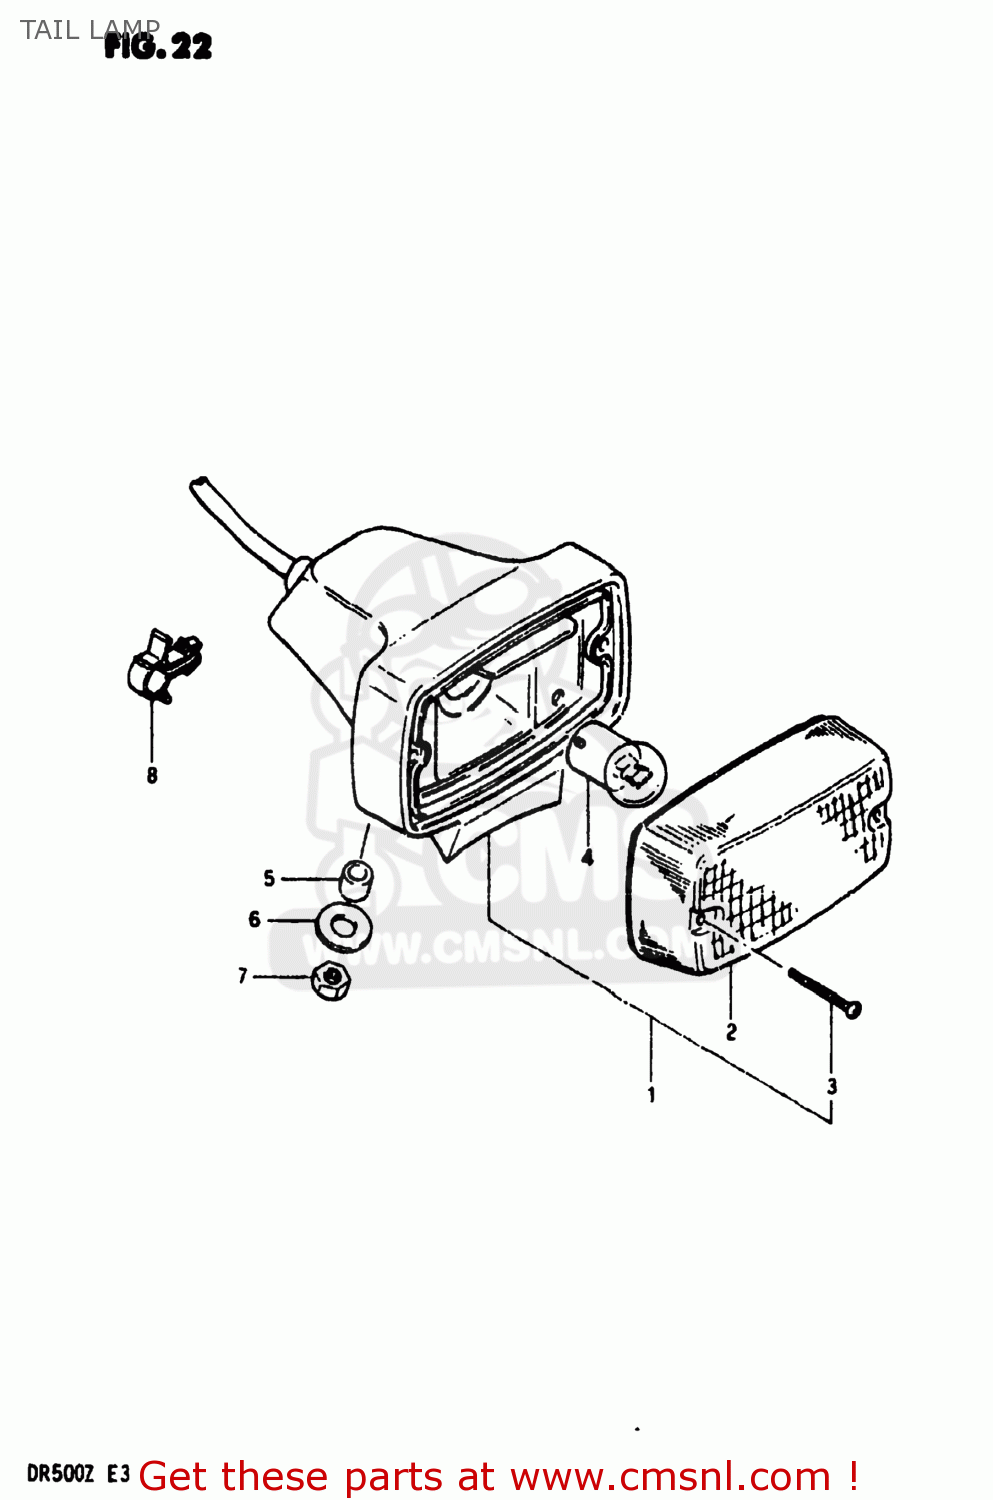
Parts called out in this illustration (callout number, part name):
1	LAMP ASSEMBLY,REAR COMBINATION
2	LENS
3	SCREW,REAR COMBINATION LAMP LENS
4	BULB(6V5W,TOKAI DENSO)
5	SPACER(6.1X9X7.5)
6	WASHER
7	NUT
8	CLAMP
